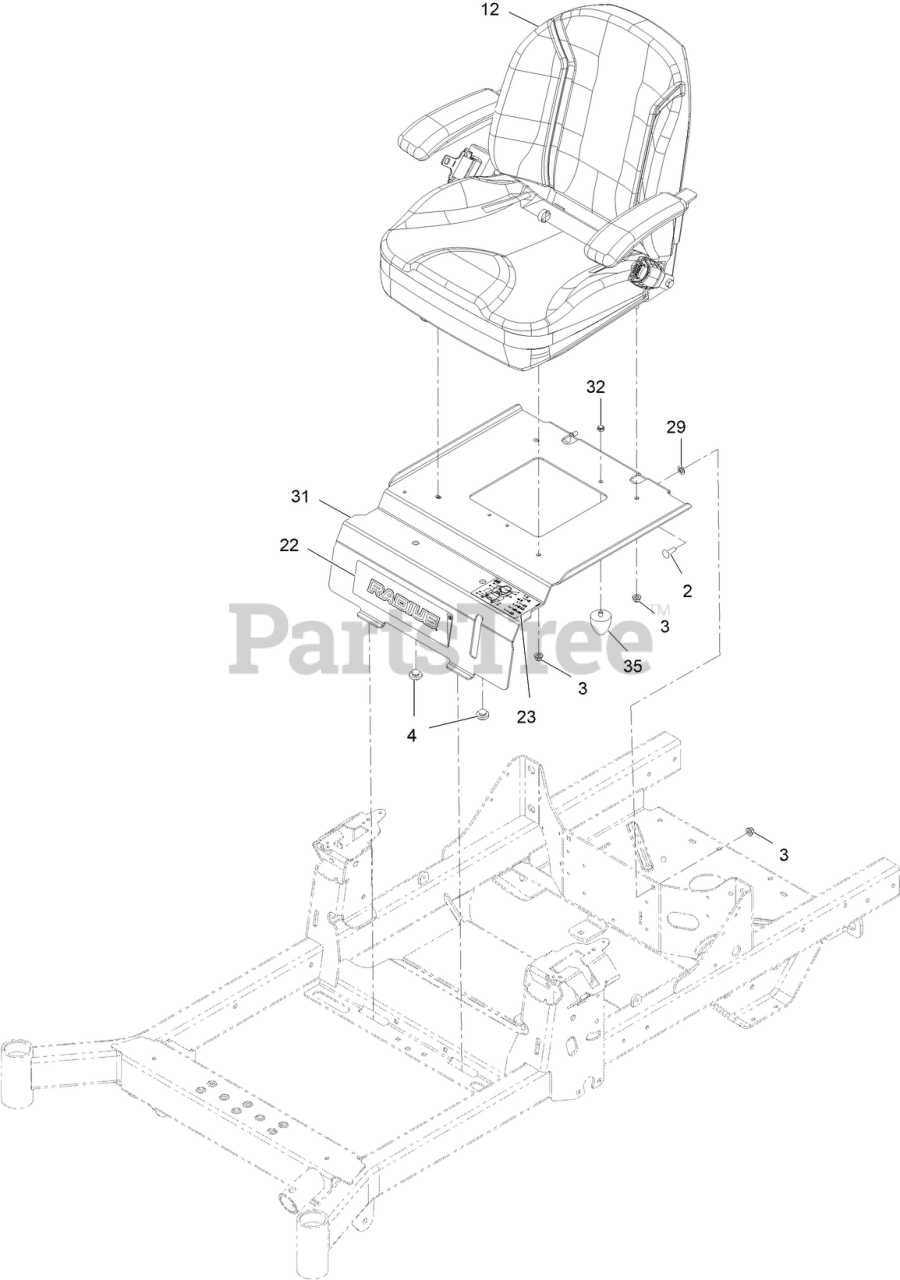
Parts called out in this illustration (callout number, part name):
2	SCREW-CARR
3	NUT-HF, NI
4	BUMPER-SEAT
12	ASM-SEAT EXMARK
22	DECAL-RADIUS LOGO
23	DECAL-AID, SERVICE
29	Washer-Retaining
31	PLATE-FIXED SEAT
32	NUT-LOCK, NI
35	BUMPER-RUBBER
